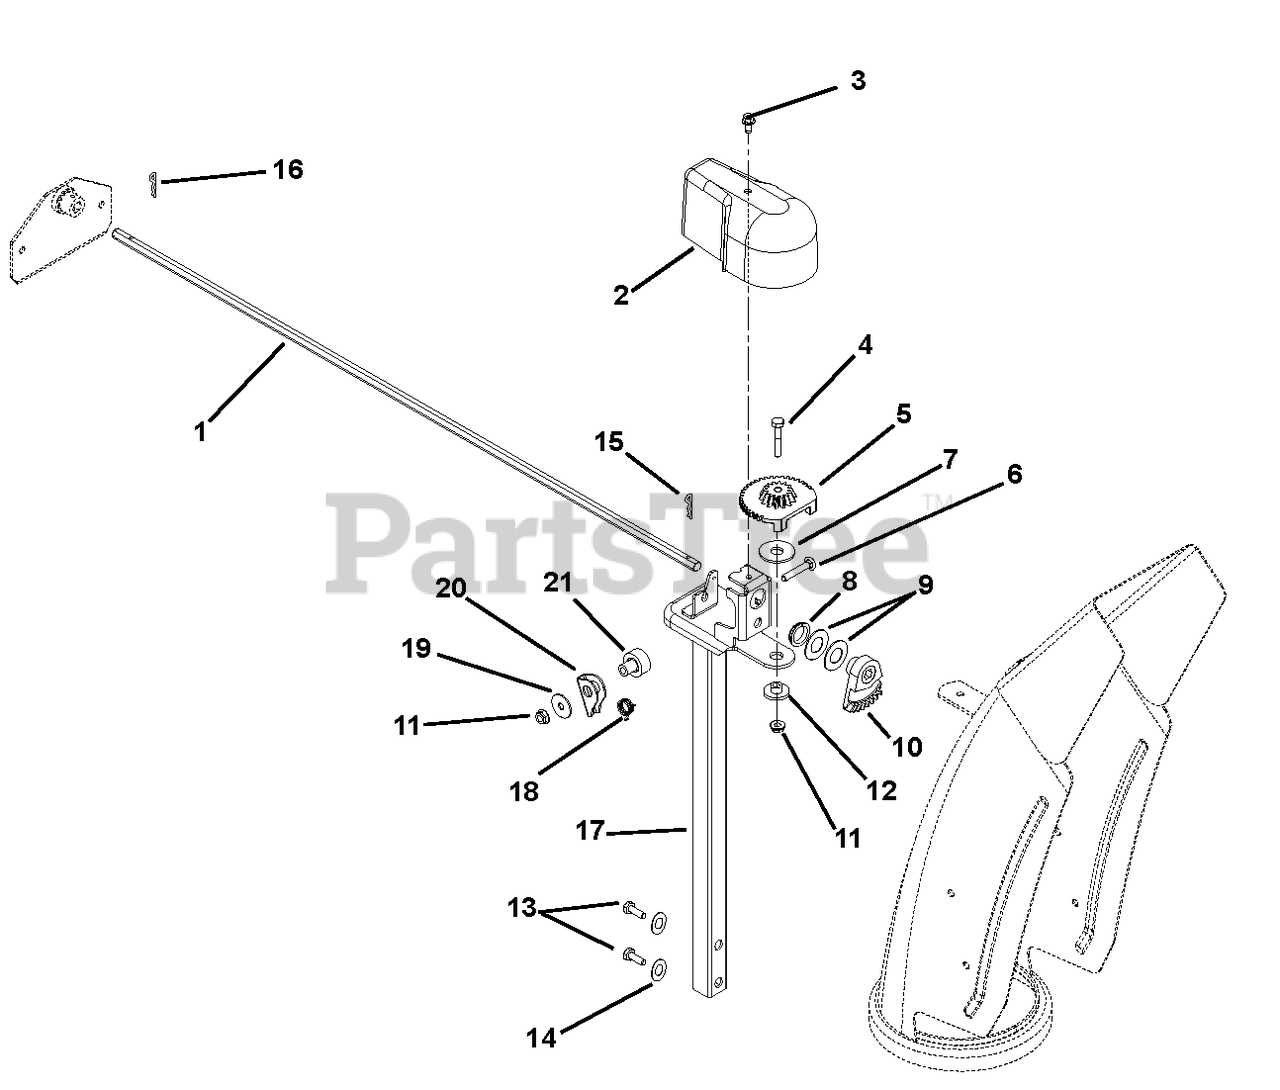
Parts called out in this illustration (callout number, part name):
1	ROD, CHUTE ROTATION-HEX
2	COVER, CHUTE GEAR
3	SCR-TAP .25-20X.50 HWH TR YWZ
4	@BLT-HEX .25-20X1.50 GR5 YWZC
5	GEAR, CHUTE
6	@BLT-RDHDSQNK .25-20X1.50 G5YZ
7	WSHR-FLT-NYL .515X1.375X.093
8	BUSHING, POLYLINER-.75 SNAPIN
9	WSHR-FL-STL.754X1.125X.062YWZC
10	GEAR, CHUTE-ACTUATION
11	@NUT-LK-TOP-FLG .25-20 YWZC
12	BSHG-FLG .265X.477X.375X1.00
13	@BLT-HEX .38-16X1.75 GR5 YWZC
14	@WSHR-LK .38X.094 REG YWZC
15	CLIP, SPRING
16	HAIRPIN, #7 CLIP .094X2.31 YWZ
17	PEDESTAL, CHUTE - QUICK STICK
18	SG-TORS
19	WSHR-FL-STL .281X1.000X.063
20	ARM, LOCKING
21	BUSHING, LOCK ARM
